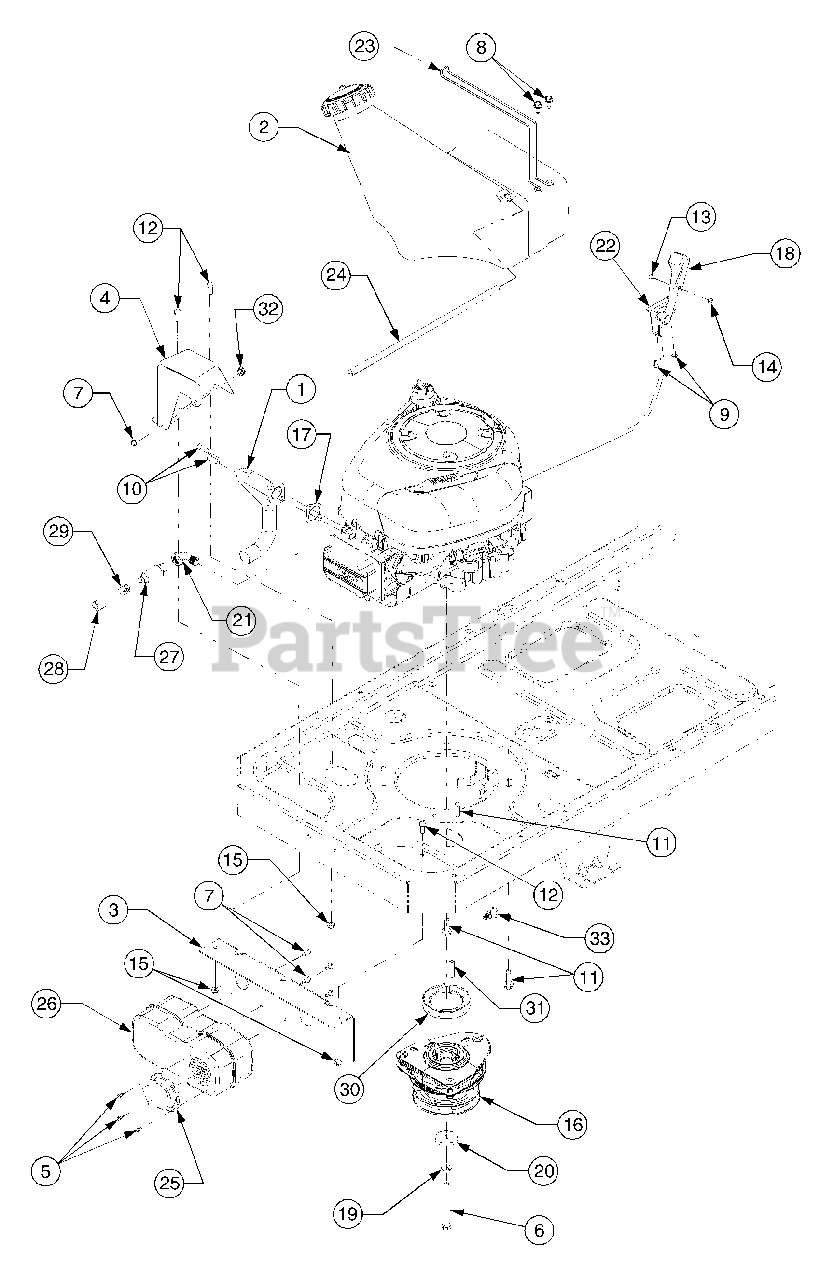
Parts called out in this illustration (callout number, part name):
1	Tube, Exhaust
2	Cap, Fuel
3	Bracket, Muffler Mounting
4	Shield, Muffler Tube Heat
5	Screw, Hex Wash. Hd. Tapp #8-18 x .5
6	Screw, Hex Cap, 7/16-20 x 4.0 GR5
7	Screw, Hex Wash. Hd. Tapp 1/4-20 x .5
8	Screw, Hex Wash. Hd. Tapp 5/16-12 x .75
9	Screw, Hex Wash. Hd. Tapp #12-16 x .5
10	Screw, Socket Hd. 5/16-18 x .75
11	Screw, Hex Wash. Hd. Tapp 3/8-16 x 1.25
12	Screw, Hex Cap, 5/16-18 x .75 GR5
13	Screw, Truss Hd. Mach. #8-32 x .375
14	Nut, Hex, #8-32
15	Nut, Hex Insert Lock, 5/16-18 GR5
16	Clutch Assembly, Electric PTO, (GT1-JD08)
16	Clutch Assembly, Electric PTO, (GT1A-MT-09)
17	Gasket, Exhaust (272293)
18	Knob, Throttle Control
19	Washer, Lock, 7/16
20	Washer, Flat, .438 x 1.75 x .25
21	Fitting, Elbow
22	Cable, Throttle, 39.0 Lg
23	Wire, Tank Mounting
24	Hose, Fuel Line
25	Deflector, Muffler
26	Muffler
27	Valve, Oil Drain
28	Hose, Oil Drain Extension
29	Cap, Oil Drain Valve
30	Pulley, Drive, 3.25 Dia.
31	Key, Square, 1/4 x 2.25, use with PTO Clutch 717-04127
31	Key, Square, 1/4 x 1.5, use with PTO Clutch 717-04183
32	Nut, Hex Sems, 1/4-20
33	Clip, Cable Retainer
